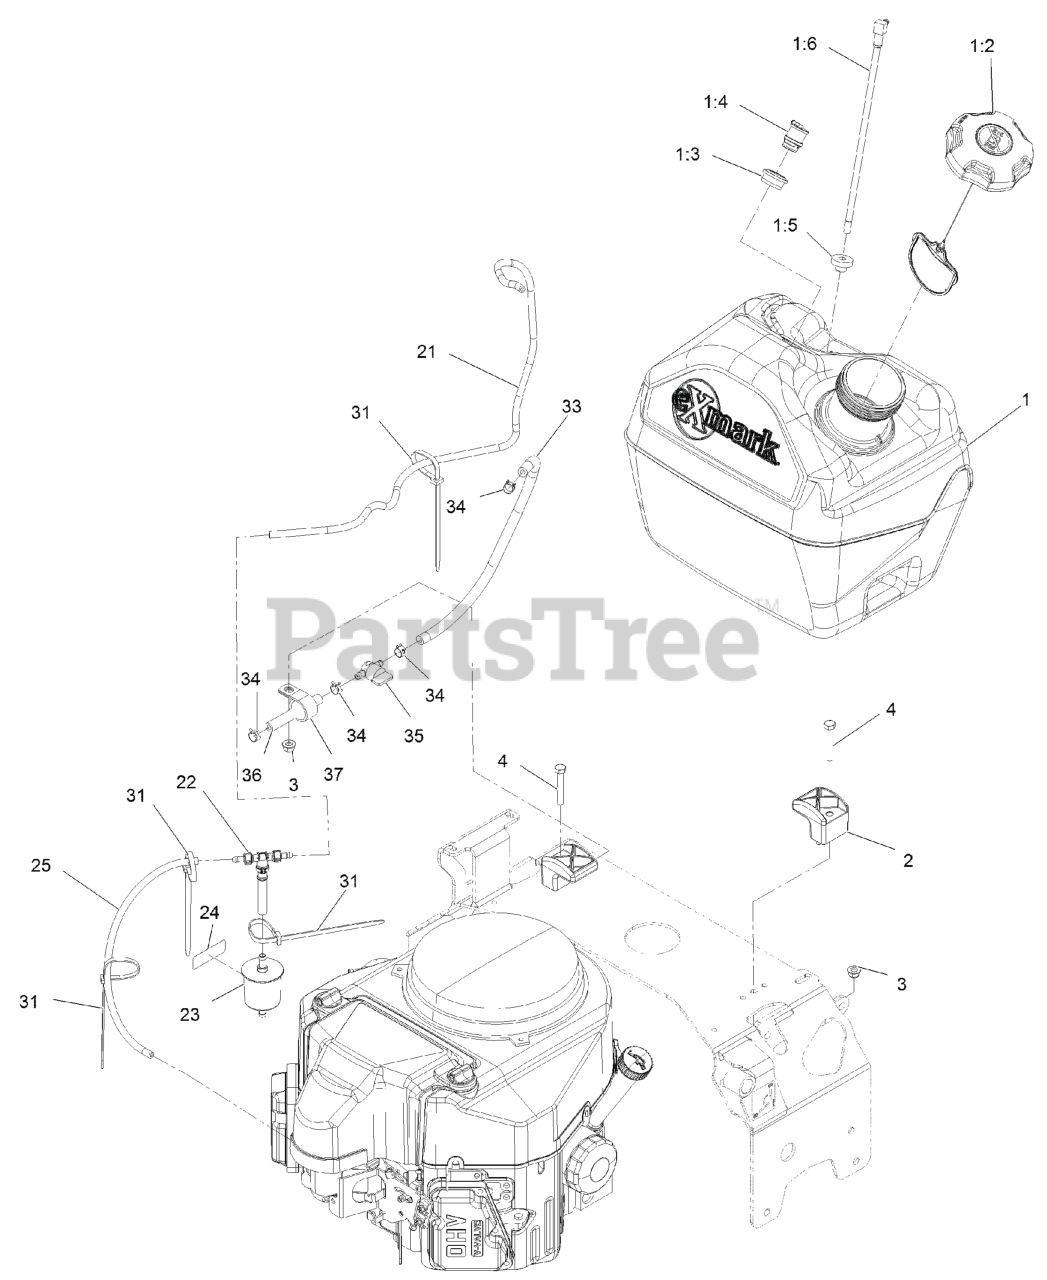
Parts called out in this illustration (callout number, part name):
1	ASM, FUEL TANK 5 GAL
1:2	CAP-FUEL, RATCHETING
1:3	GROMMET
1:4	VALVE-VENT, FUEL
1:5	BUSHING
3	NUT-HF, NI
4	SCREW-HH
21	HOSE, EMISSIONS
22	TEE AND CHECK
23	FILTER-FUEL
24	DECAL-FILTER, EMISSIONS
25	HOSE-FUEL
31	TIE-PLASTIC
33	HOSE-FUEL
34	CLAMP-HOSE
35	VALVE-FUEL
36	HOSE-FUEL
37	CLIP-LOOM
